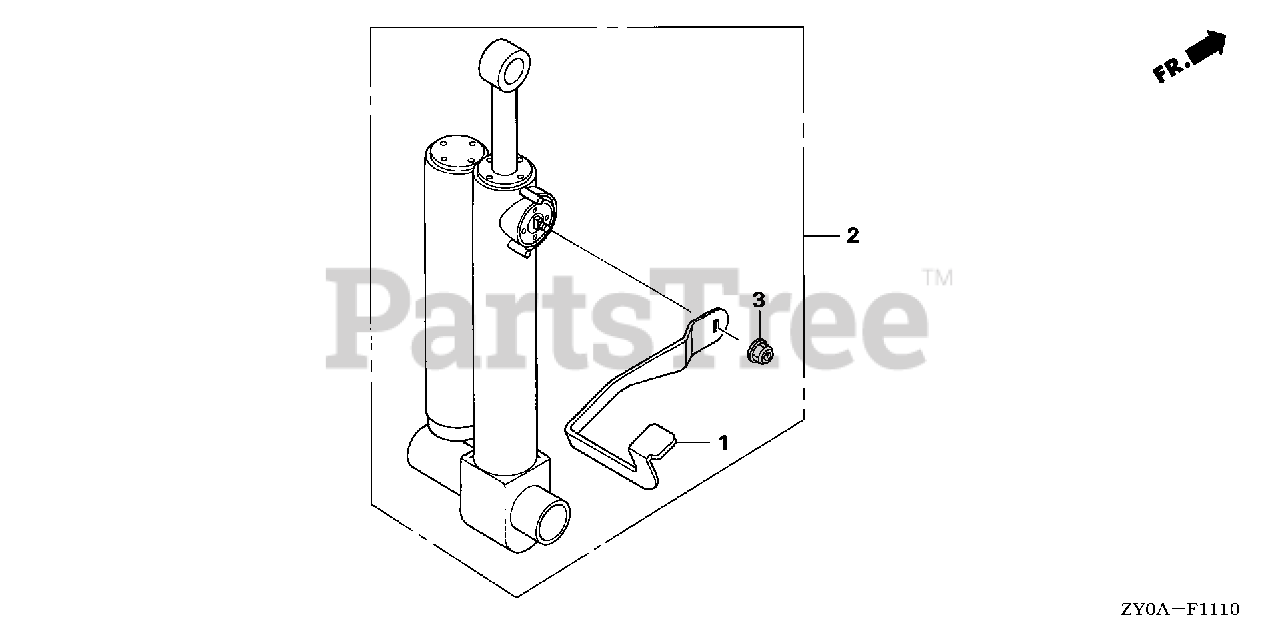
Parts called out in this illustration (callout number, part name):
1	LEVER, TILT
2	SHOCK ABSORBER ASSY., GAS
3	NUT, SELF-LOCK (6MM)
